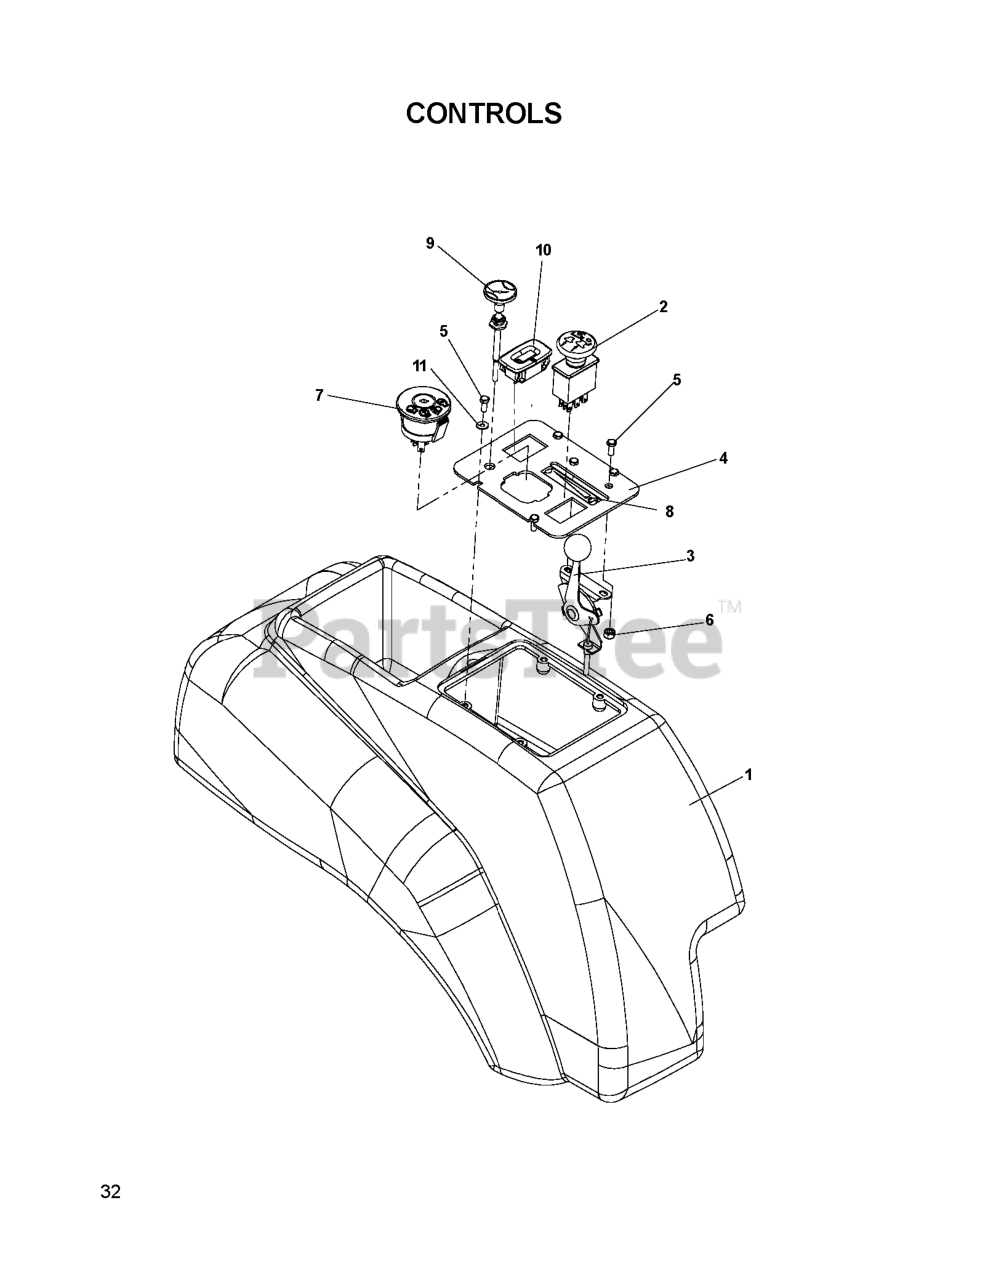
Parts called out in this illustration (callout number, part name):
1	FENDER CONSOLE
2	RP.SWITCH, BLADE
3	THROTTLE CABLE
4	CONSOLE PLATE, BLACK
5	HCS #10-24 X 1/2
6	NUT 10-24 NYLOC
7	RP IGNITION SWITCH
8	DECAL, THROTTLE
9	CHOKE CONTROL
10	HOUR METER
11	WASHER #10
